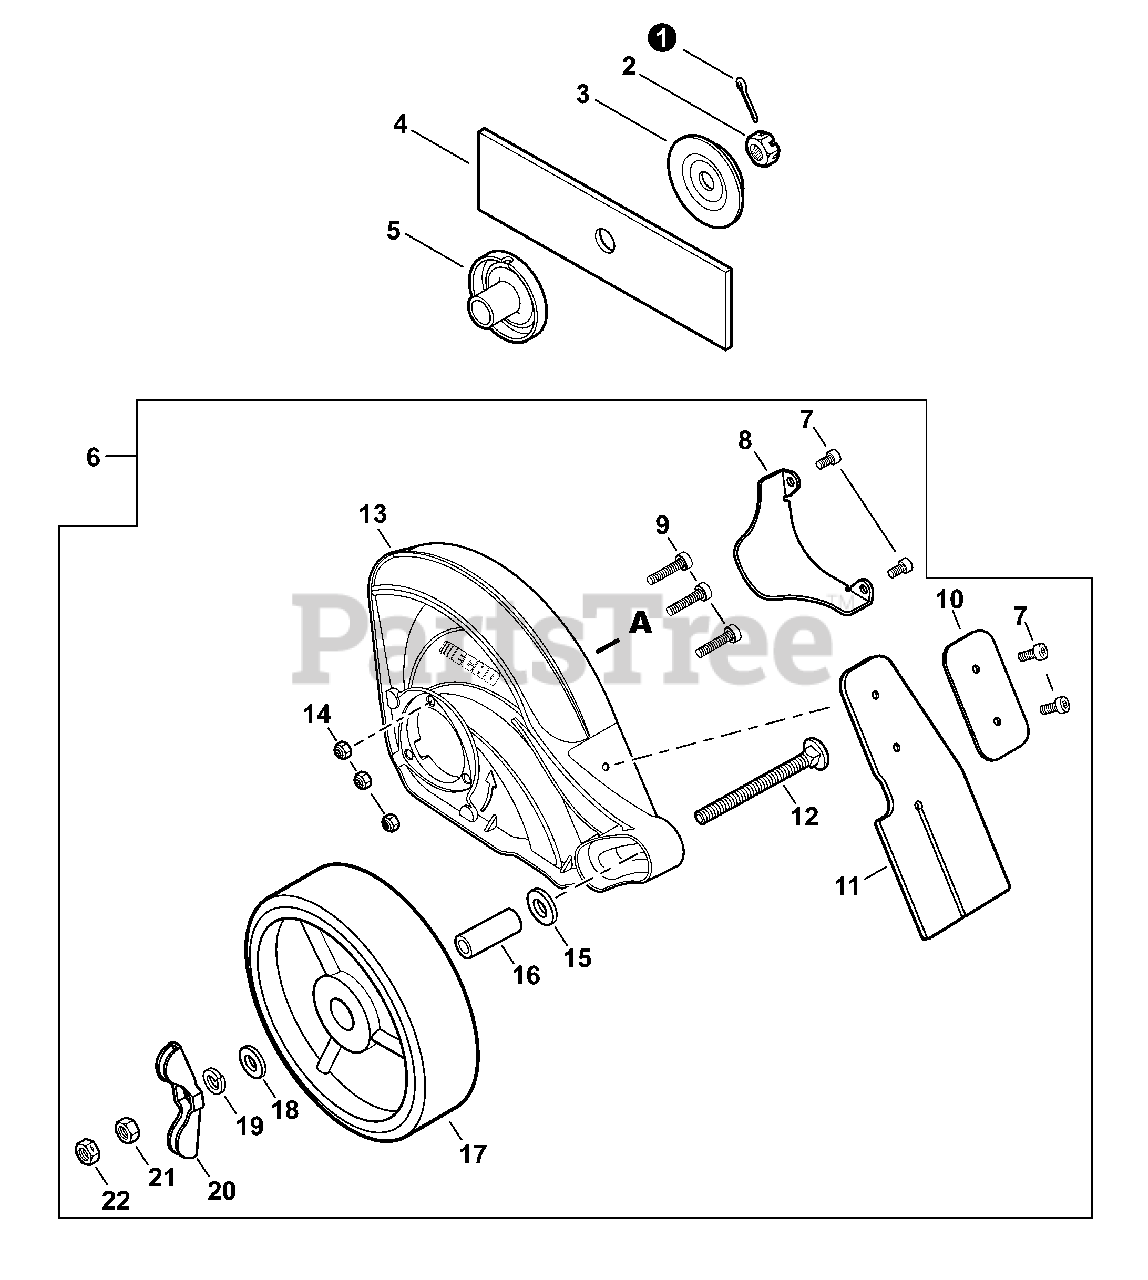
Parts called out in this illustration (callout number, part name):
1	PIN, COTTER 2×22
2	NUT 10×1.25 LH
3	PLATE, ADAPTOR - LOWER
4	BLADE - 2 PK
5	PLATE, ADAPTOR - UPPER
6	SHIELD KIT, EDGER
7	BOLT, TORX 4×12
8	GUARD, SHIELD
9	BOLT, TORX 5×20
10	PLATE, FLAP
11	FLAP, DEBRIS
12	BOLT M8-1.25×80 MM
13	SHIELD, BLADE
14	NUT, LOCK M5
15	WASHER, SPRING 10
16	COLLAR 12
17	WHEEL
19	WASHER, SPRING 8
20	KNOB, FASTENER
22	NUT, LOCK M8
